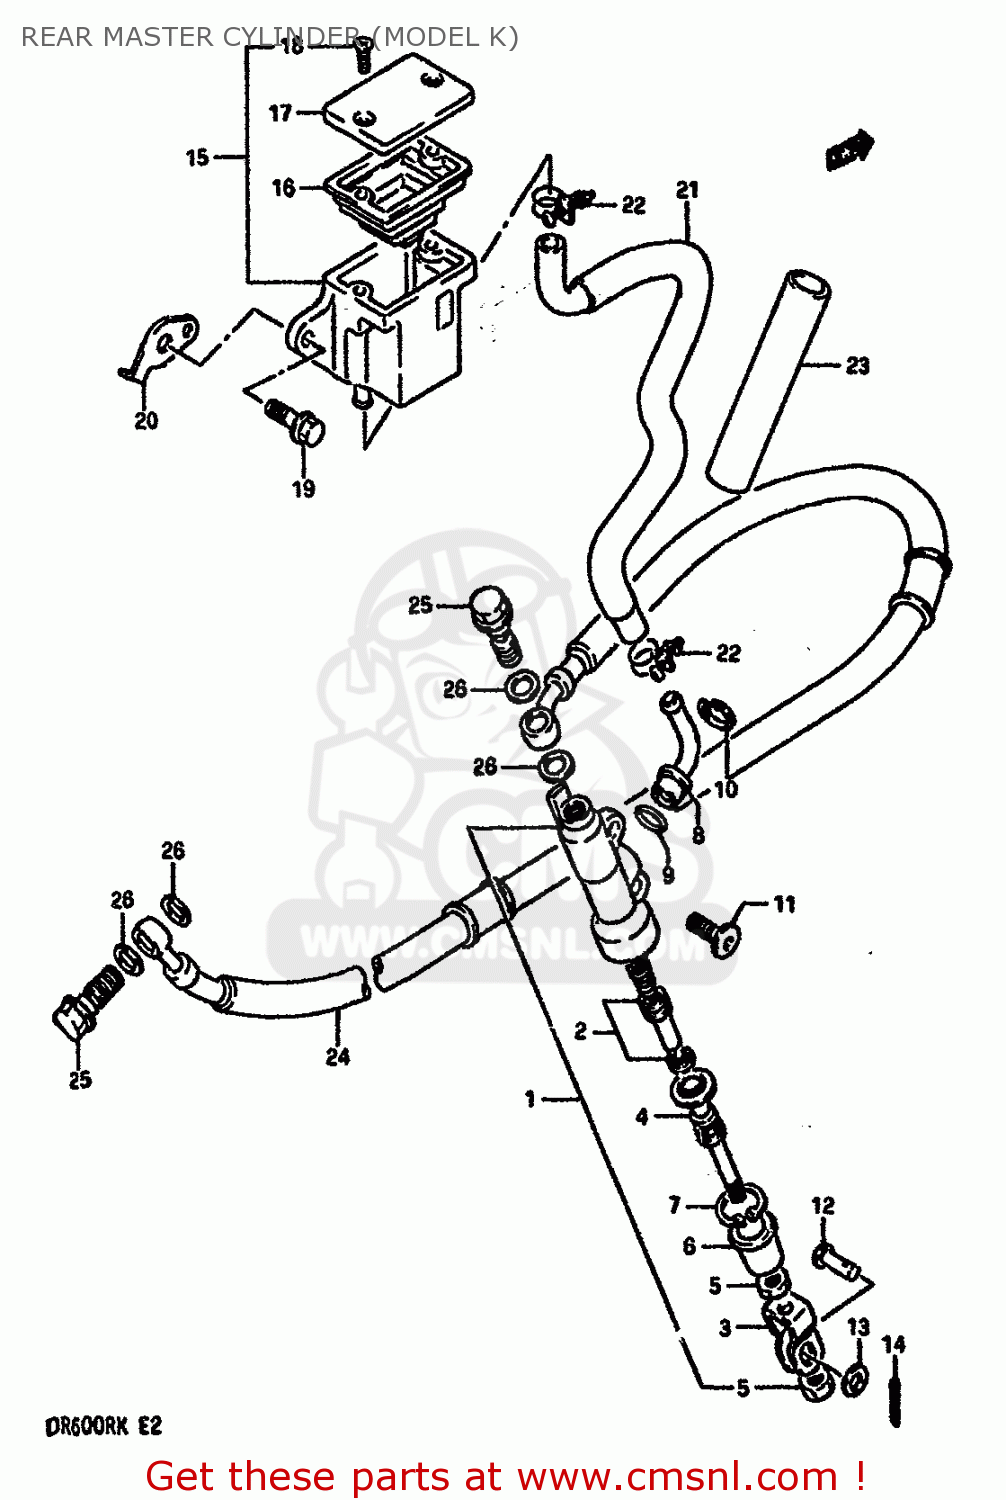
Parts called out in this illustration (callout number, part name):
1	CYLINDER ASSY,RR MASTER
2	PISTON/CUP SET
3	YOKE
4	ROD,PUSH
5	NUT
6	BOOT
7	CIRCLIP
8	CONNECTOR
9	O RING
10	CIRCLIP
11	BOLT(6X18)
12	PIN
13	WASHER
14	PIN
15	TANK ASSEMBLY,RESERVOIR
16	DIAPHRAGM
17	CAP
18	SCREW
19	BOLT
20	PLATE,RESERVOIR TANK
21	HOSE,RESERVOIR TANK
22	CLAMP
23	SHIELD,HOSE
24	HOSE,REAR BRAKE
25	BOLT UNION
26	WASHER(10X15X1.5)
